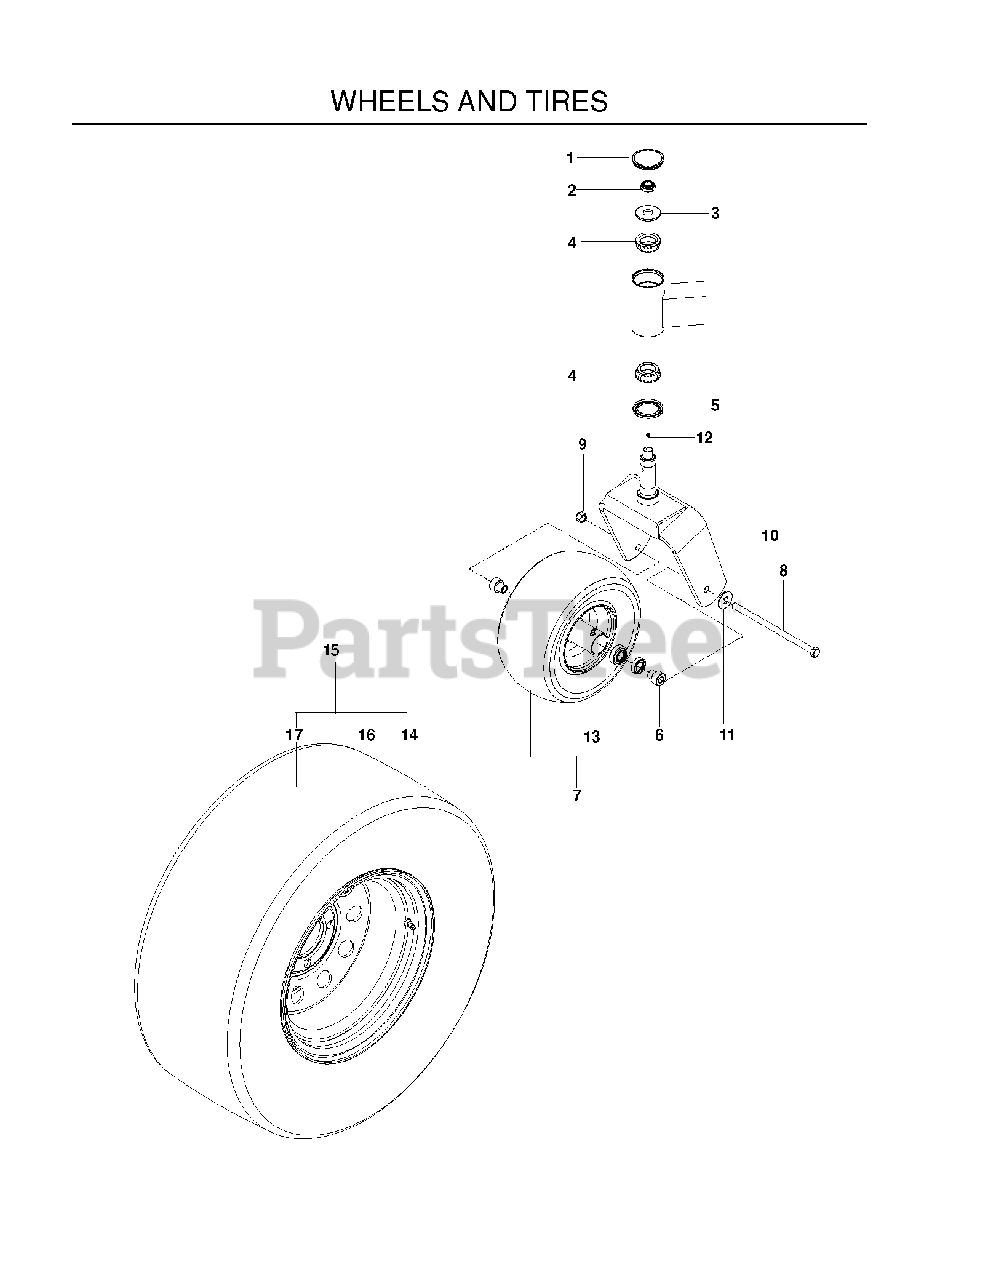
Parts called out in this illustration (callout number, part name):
1	CAP, DUST
2	NUT, 3/4-16 HEX THIN NYLOC ZD
4	CONE, LM67048
5	SEAL, BEARING
6	AXLE SPACER
7	TIRE, 13 X 6.5-6 NO FLAT
8	HEX SCREW 1/2-13 X 9.5 GR5
9	NUT, 1/2-13 HEX FLG NYLOC ZD
10	FORK, CASTER
11	WASHER 1/2" FLAT
13	ZERK
14	VALVE STEM TR-412
15	WHEEL, DRIVE, 26 X 12
16	RIM, 12 X 8.5, CENTERED
17	TIRE, 26-12 X 12
